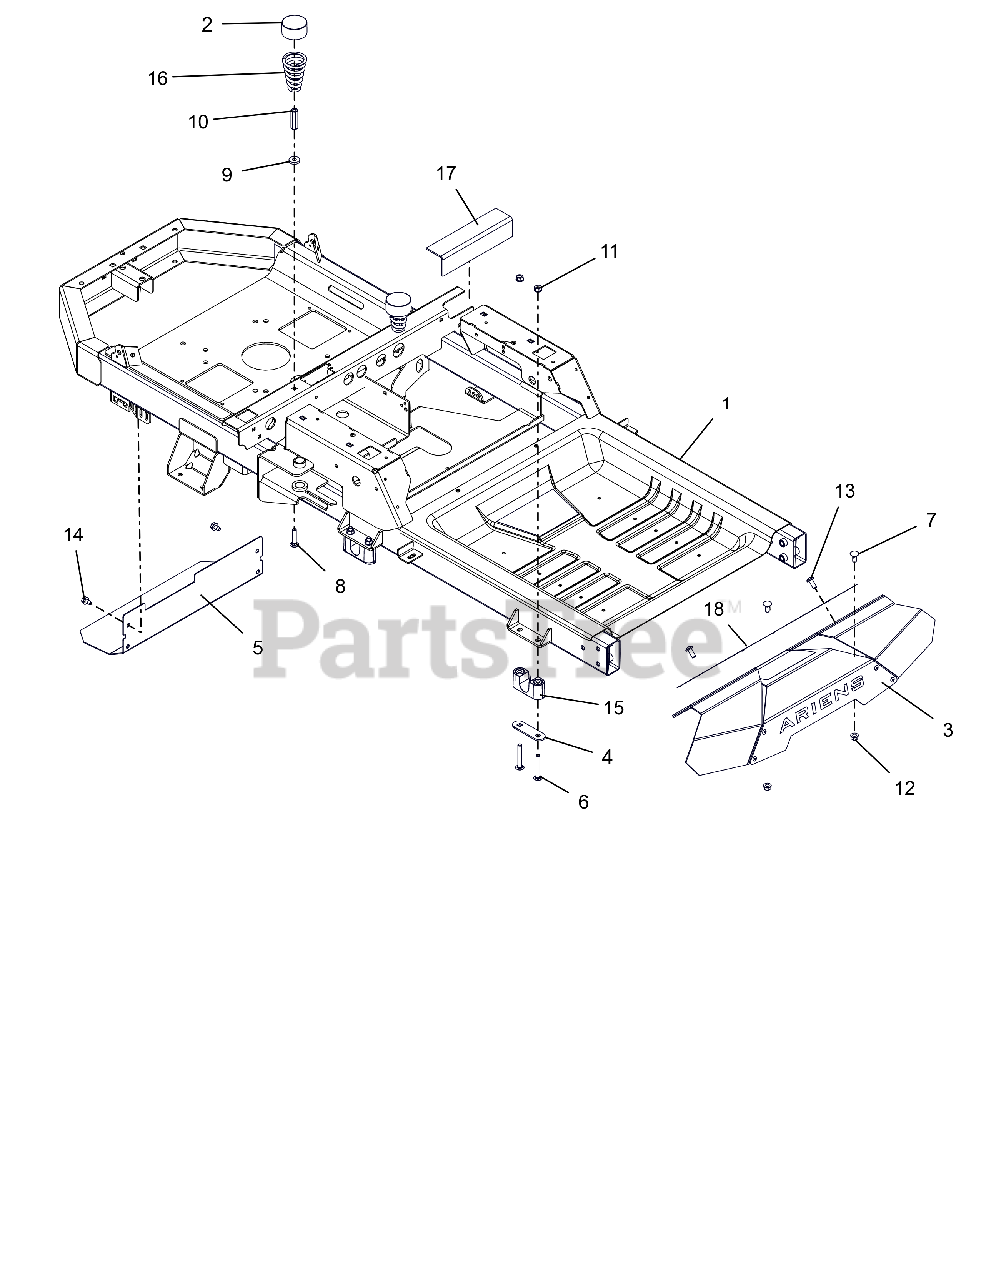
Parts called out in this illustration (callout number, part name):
1	KIT, IKON-X/XL FRAME (2016)
2	HUB CAP
3	KIT, IKON FOOT REST W/DECAL
4	PLATE, BEARING SUPPORT
5	HEAT, SHIELD
6	BLT-RDHDSQSHNK .31-18X2.25 YWZ
7	BLT,RHSN .31-18X.75 G5 ZCC
8	BLT,RHSN .31-18X1.50 G5 ZCC
9	WSHR, FLT .328X.870X.179 ZCC
10	NUT, COUPLING 5/16-18 X 1 3/4
11	NUT,LK-CTR-FLG .31-18 GF ZCC
12	NUT-LK-TOP-FLG .312-18 GF ZCC
13	SCR-RDHDSKTAP .31-18 X .75
14	SCR,TAP .312-18X.50 HWH TR ZCC
15	BSHG, DECK LIFT PIVOT
16	SPRING, SEAT
17	PAD, RUBBER-TANK
18	GRIP TAPE, FOOT PLATE
